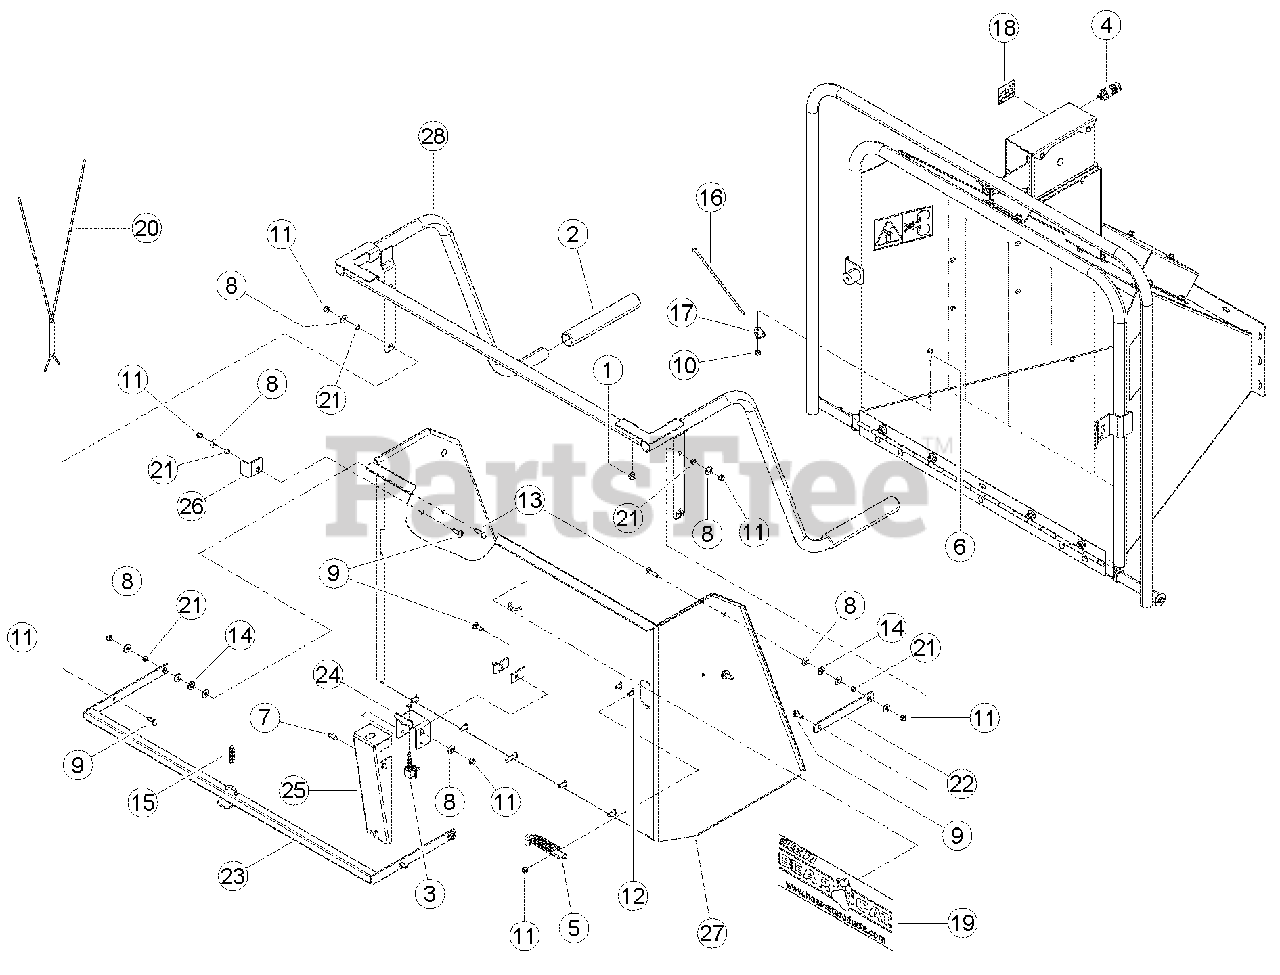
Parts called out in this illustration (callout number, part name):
1	BUMPER, RUBBER
2	GRIP, 1.219 X 10.00
3	SWITCH, N/C MOMENTARY PLUNGER
4	SWITCH, N/O MOMENTARY PUSHBUTTON
5	LATCH, RH HINGE
6	BOLT, 1/4 X 1 HEX HD GR5 ZP
7	SCREW, 11/32 X 7/8 HWH AB THREAD ZP
8	WASHER, 5/16 FLAT ZP
9	BOLT, 5/16 X 1 CRG GR5 ZP
10	NUT, 1/4 NE NYLOCK ZP
11	NUT, 5/16 NE NYLOCK ZP
12	BOLT, 5/16 X 3/4 CRG GR5 NC ZP
13	BOLT, 5/16 X 1-1/4 CRG GR5 ZP
14	WASHER, 5/16 ID X 7/8 OD NYLON FLAT
15	SPRING, 1/2 X 2.00 LG ZP
16	STRAP, 11 IN. BLACK TIE
17	CLAMP, CABLE MOUNT
18	DECAL, RESET/OVERRIDE
19	DECAL, BEARCAT WEB
20	HARNESS, SAFETY BAR
21	SPACER, IDLER PIVOT
22	LINK, PARALLEL
23	WELDMENT, KNEEBAR PIVOT
24	BRACKET, SWITCH
25	SHIELD, KNEEBAR SWITCH
26	LOCK, SAFETY BAR
27	WELDMENT, EXTENSION TRAY W/ TABS
28	WELDMENT, KNEEBAR
